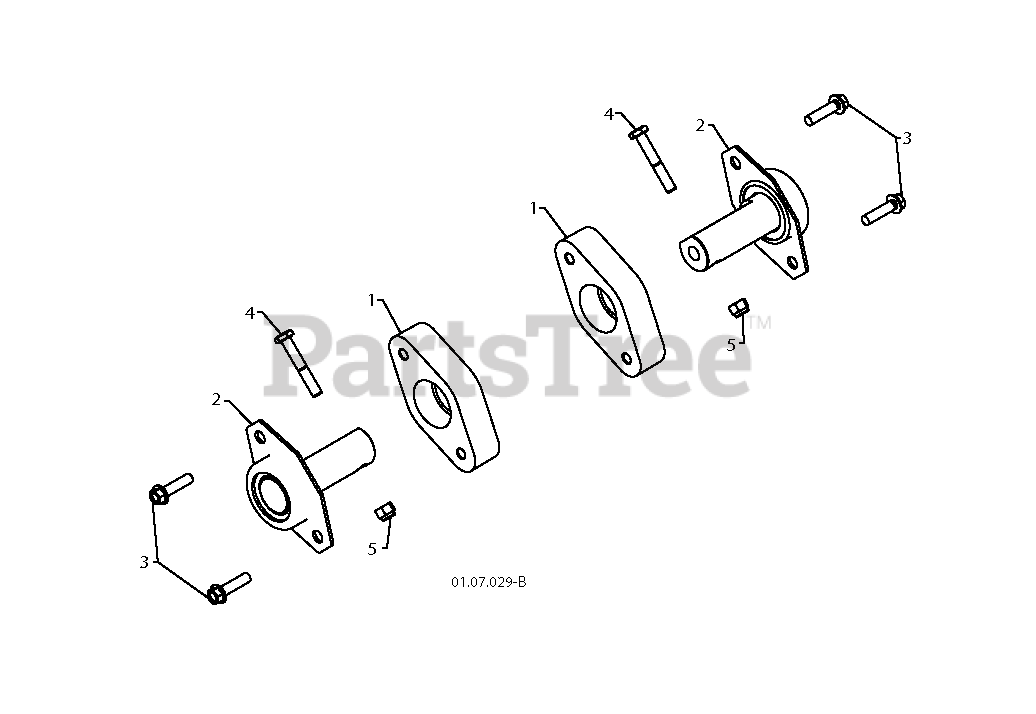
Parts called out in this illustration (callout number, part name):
1	BEARING RETAINER, PLASTIC
2	RP BEARING.BALL.AUGER.FLAT.
3	SCREW, HEX HD 5/16X1
4	SCREW.HEX.HD1/4-20X
5	LOCKNUT
